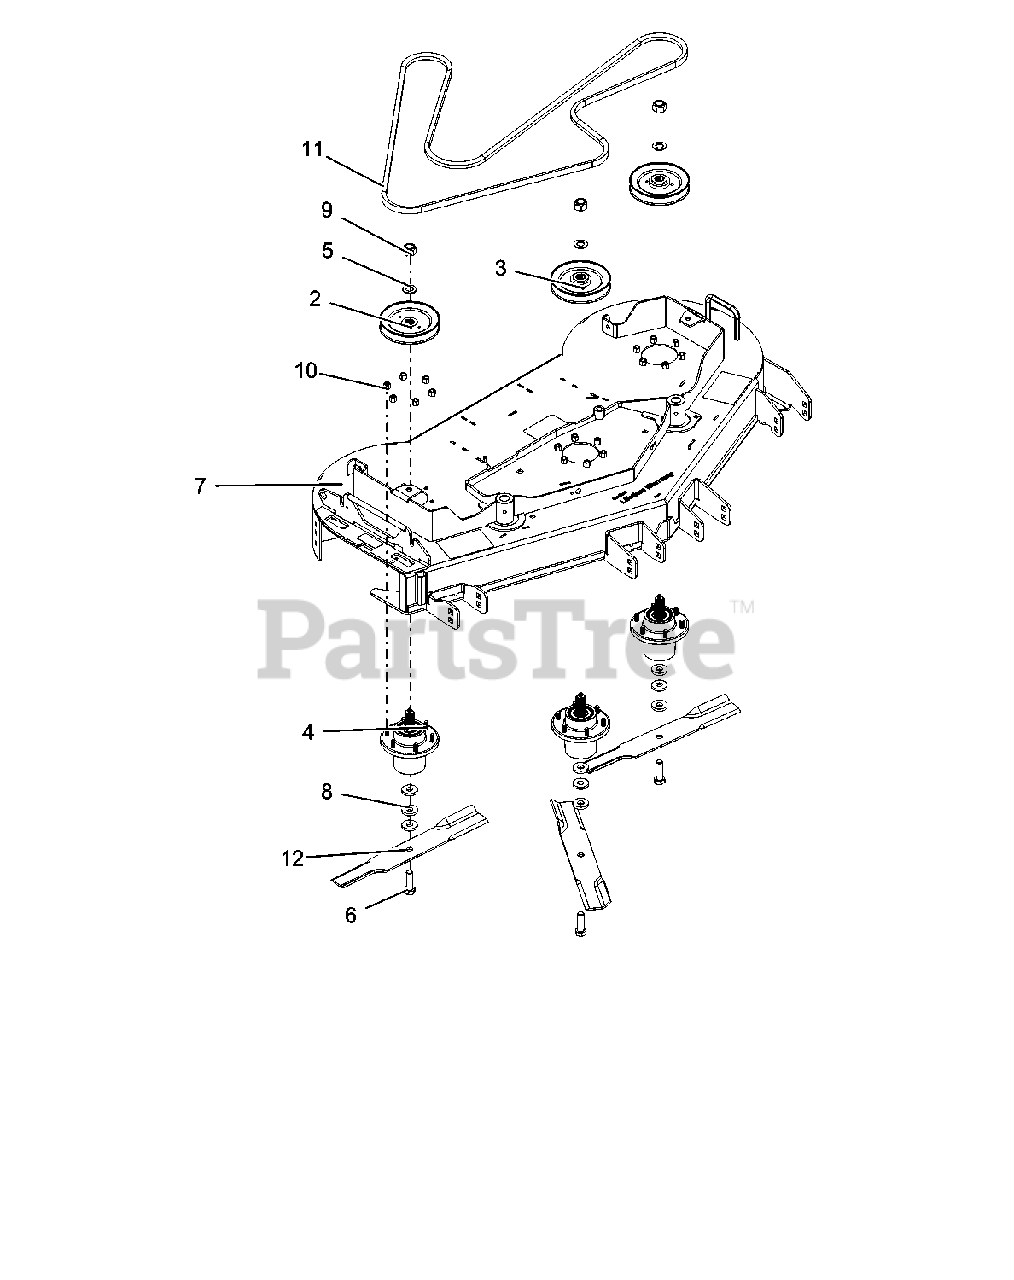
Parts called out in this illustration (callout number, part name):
2	PULLEY, SPINDLE 5.75 X .76-BLACK
3	PULLEY, SPINDLE 5.75 X .25-BLACK
4	ASSY, SPINDLE HOUSING
5	WASHER, .75X1.3125X.120
6	BLT-HEX .62-11X2.00 GR8 YWZC
7	ASSY, 52 FLWLK DECK W/DECALS
8	WSHR-FL-STL .630X1.50X.25 YWZC
9	LOCKNUT, 3/4-16 CROWN GR5 Y
10	NUT-LK-NYL .38-16 YWZC
11	BELT, HB 131.0 EL AMD
12	BLADE, 18.000 X .80 LIFT
